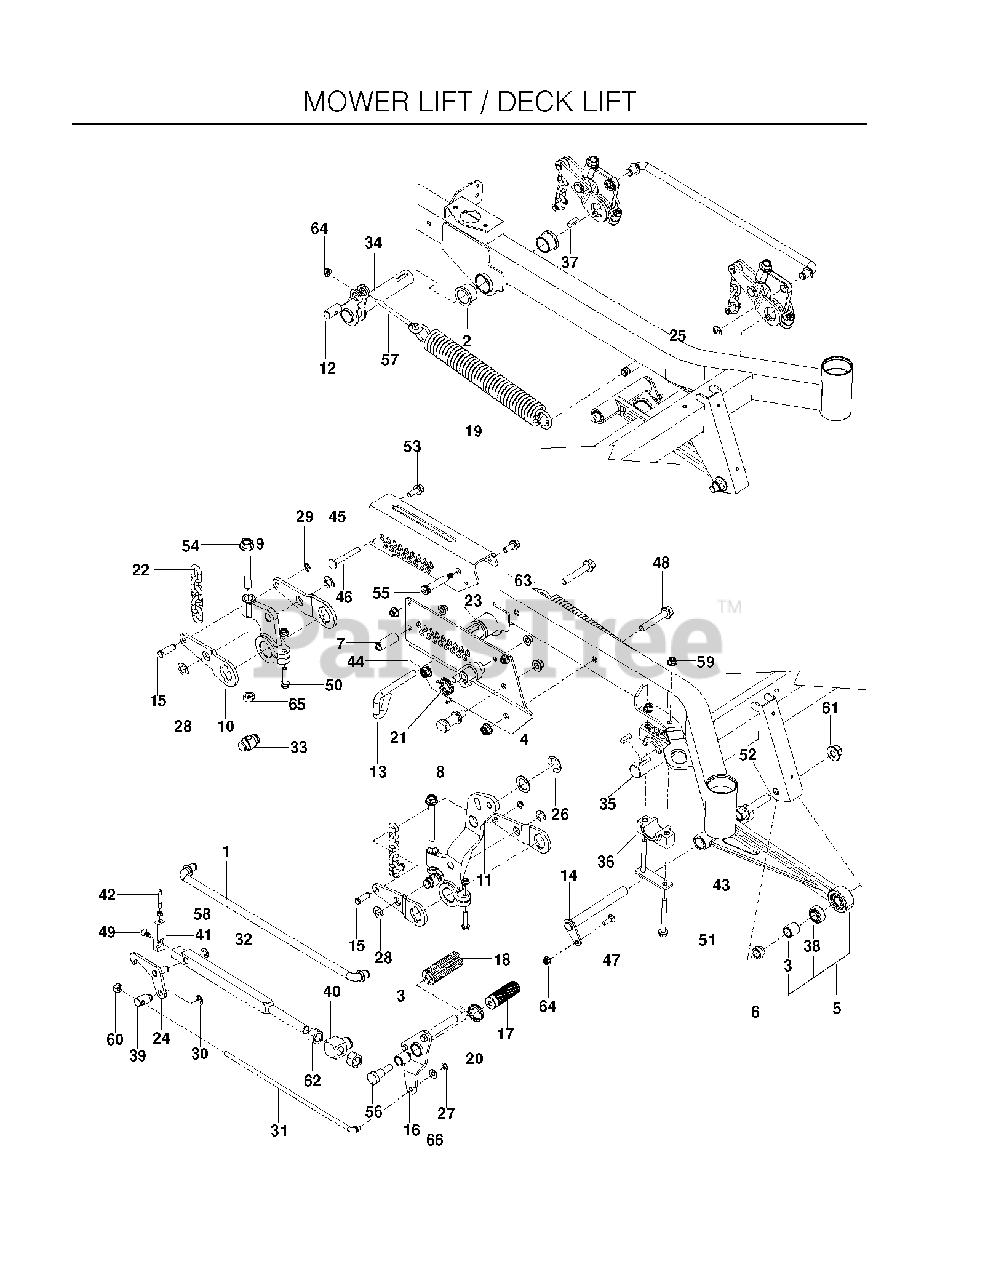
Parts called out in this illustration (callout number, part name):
1	ROD, LIFT
2	BUSHING, FLANGE 1.25 X 1.0
3	BUSHING, SLEEVE 3/4 X 1.0
4	MACHINE BUSHING
5	ASSEMBLY, STRUT
6	SPACER, STRUT
7	SPACER, HEIGHT PLATE
8	GUIDE, HEIGHT BAR
9	ARM, CAST LIFT
10	ARM LIFT BLK
11	ARM, LIFT LEVER
12	PIVOT, SPRING
13	PIN, HEIGHT
14	PIN, STRUT
15	PIN, 7/16 CLEVIS
16	PEDAL, RELEASE WLDMT
17	PEDAL, DECK HEIGHT
18	PAD, FOOT PEDAL
19	SPRING, EXTENSION
20	SPRING, TORION
21	SPRING, TORSION
22	LIFT CHAIN
23	LATCH, TRANSPORT WLDMT
24	LATCH, HEIGHT WLDMT
25	5/8 E-RING
26	E-RING 1"
27	E RING 3/8"
28	E RING 3/4
29	RING, E, 7/16
30	E-RING 1/2
31	ROD, HEIGHT LATCH
32	BAR, HEIGHT
33	SHAFT, LIFT TRUNION
34	SHAFT, RR LIFT
35	SHAFT, LIFT, FT
36	BLOCK, PILLOW
37	KEY, 5/16 SQ X 1.0
38	BALL JOINT, 3/4" SWIVEL
39	SWIVEL, HEIGHT LATCH
40	SWIVEL, HEIGHT BAR
41	CAP, HEIGHT BAR
42	LINK, INDICATOR
43	PLATE, PILLOW BLACK
46	3/8-16 X 3` CARR BOLT
47	RHSNB 5/16C X 1
48	HFFS 1/2-13 X 3 GD 5 ZD
49	SCREW, 5/16-18 X 3/4 FLAT HEX
50	HHFS 5/16-18 X 1.5 GD 5
51	HHFS 3/8-16 X 3.5 GD 5 ZD
52	HHFS 5/8-11 X 3.0 GD 8 ZD
53	HHFS 3/8-16 X 1 GRD 5 ZD
54	HHFS 1/2-13 X 4 GR 5
55	BOLT, SHOULDER, 1/2 X 2.25
56	BOLT, SHOULDER
57	EYE BOLT 4.5`
58	NUT 1/4-20 JAM
59	NUT 3/8-16 HEX FLG NYLOC ZD
60	NUT 3/8-24 JAM
61	NUT 5/8-11 FLG NYLOC ZD
62	NUT 3/4-10 HEX ZD
63	NUT, 1/2-13 HEX FLG NYLOC ZD
64	5/16-18 NYLOC FLANGE NUT
65	NUT 1/2 HEX JAM
66	WASHER 3/8 SAE FLAT
